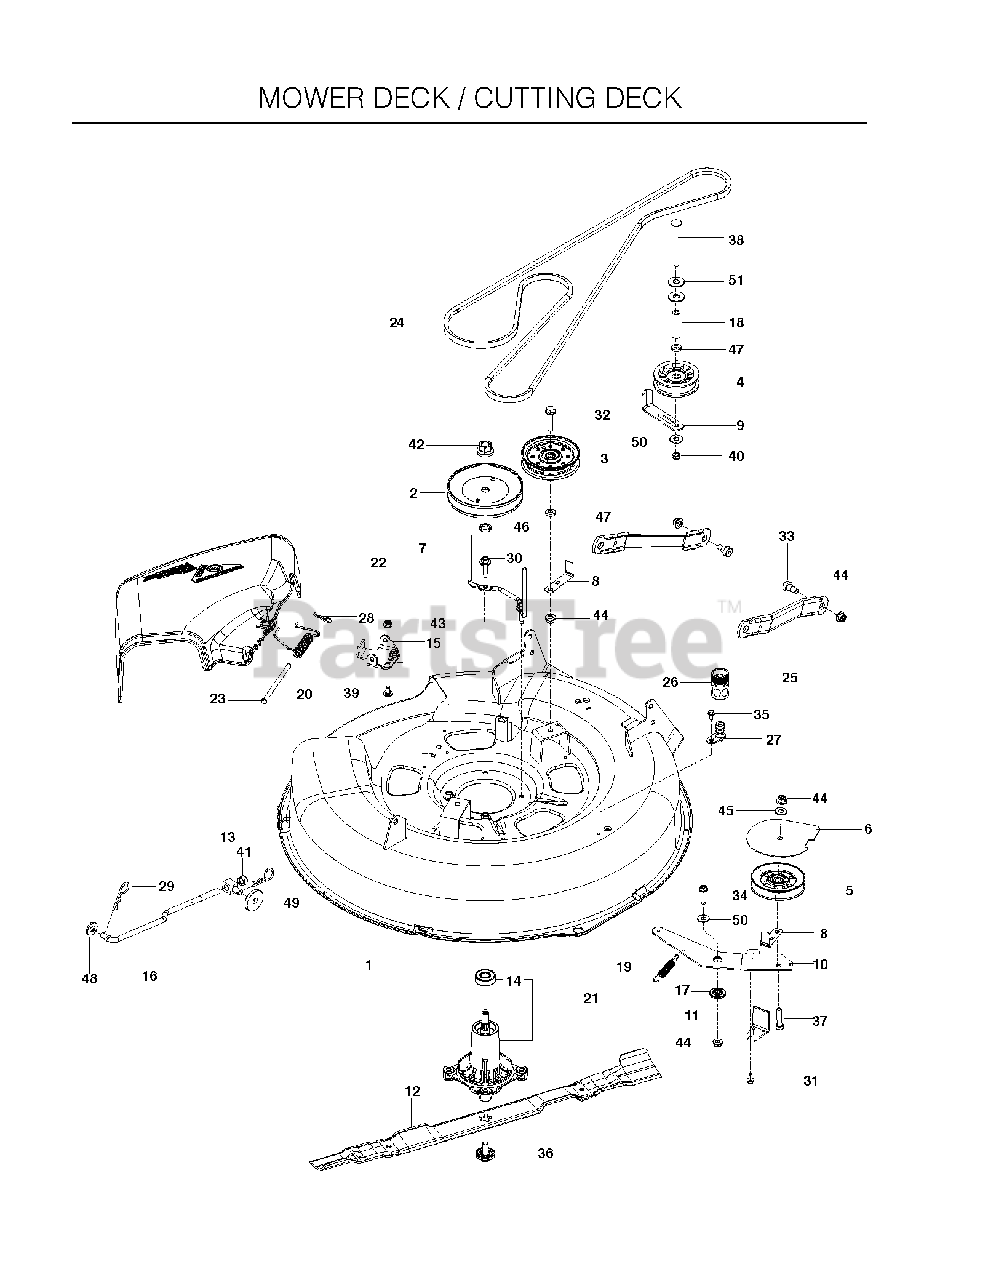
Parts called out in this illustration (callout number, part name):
1	DECK.SVC.W/DECALS.30".RZ.ORN
2	PULLEY MANDREL 5.0"
3	PULLEY.IDLER.FLAT.46.PR.DR.
4	PULLEY, IDLER RAKE & ZTR
5	Idler Pulley, 4.25
6	COVER, PULLEY, BLACK
7	BELT KEEPER.MANDREL.38"COATED
8	KEEPER, BELT, BLACK
9	GUIDE, BELT
10	ARM, IDLER 30, BLK
11	ARM, LH BRAKE
12	BLADE.MOWER.BAGGING.30"
14	BEARING, BALL
15	BRKT.DEFLECTOR.38"2005+
16	LINK LIFT SUSP. FRONT MOWER
17	SPACER.RETAINER
18	SPACER .39 ID X 2.25
19	SPRING RETURN
20	TORSION SPRING
21	MANDREL GREASABLE
22	SHIELD.DEFLECT.MWR.30S.BLACK
23	PIN-CLEVIS 5/16 DIA X 5.19 ZD
24	BELT, 100" EL
25	ARM.SUSPENSION.MOWER
26	COUPLING.QUICK CONNECT
27	PORT.WASHOUT
28	HAIRPIN #2
29	HAIRPIN #4
30	WASHER HEAD SCREW
31	SCREW- 1/4-20 X 5/8
32	BLT 3/8-16X1-3/4 WHIZLK ZN SP
33	SB 3/8-16 X 3/8 SKT HD ZD
34	BOLT 3/8-16 X 1 1/2 ZINC CLEAR
35	BOLT 1/4-20 X 1/2 HWST
36	BOLT.WASHER.ASM.7/16-2
37	HCS 3/8C X 2
38	RHSNB 3/8-16 X 4 GR5 ZD
39	CARRIAGE BOLT 5/16C X 5/8"
40	NUT 3/8-16 HEX JAM
41	NUT, 7/16-20 HEX NYLOC ZC
42	LOCKNUT - 9/16
43	5/16-18 NYLOC FLANGE NUT
44	NUT 3/8-16 HEX FLG NYLOC ZD
45	WASHER 3/8 SAE FLAT
46	WASHER-SPACER
47	WASHER 3/8 X 3/4 X .187 TK
48	WASHER 1/2" FLAT
49	SPINDLE WASHER
50	RP WASHER 3/8 FLAT
51	WASHER 7/16 FLAT ZD
